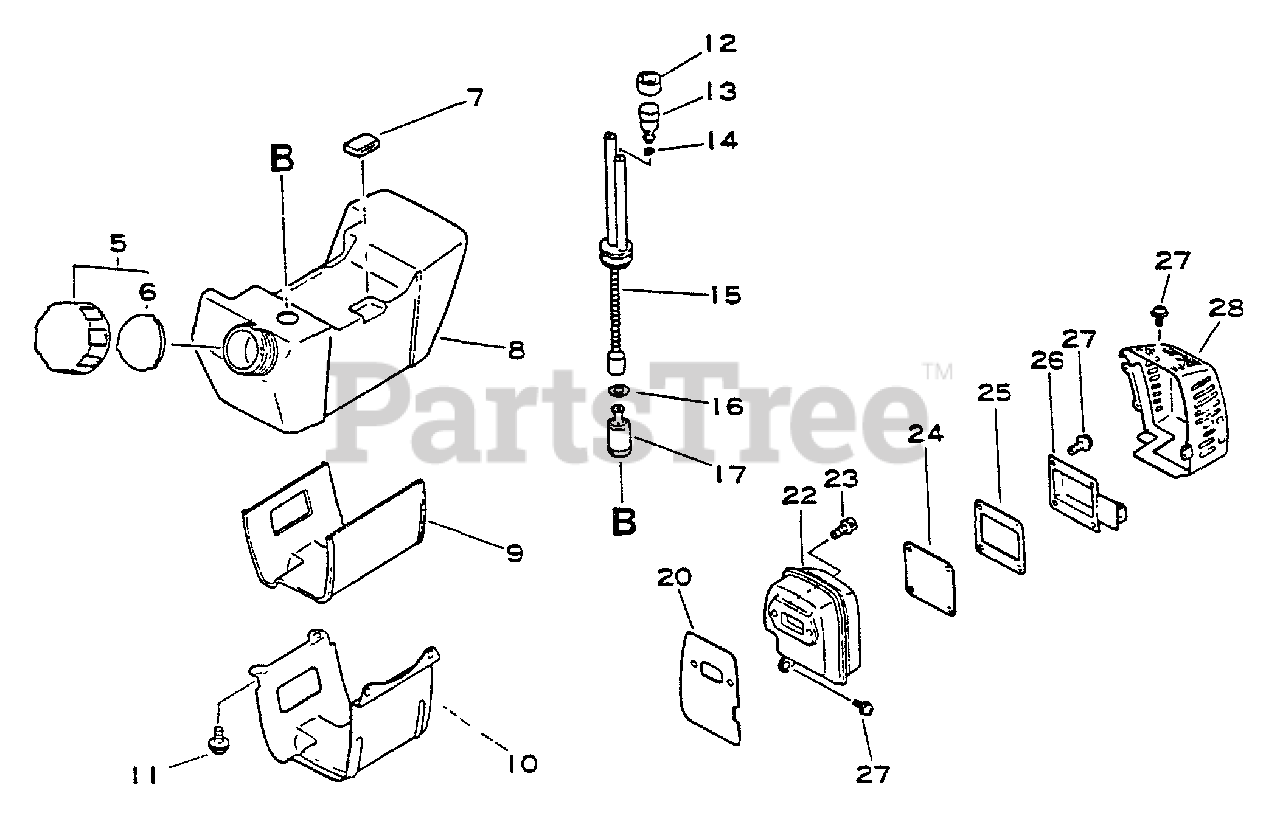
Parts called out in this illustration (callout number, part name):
5	CAP ASSY
6	GASKET, FUEL CAP
8	TANK, FUEL
10	STAND
11	SCREW 5×14
12	HOLDER, VENT
13	VENT ASSY
15	PIPE, FUEL
16	WASHER 5.5×12×0.8
17	FILTER, FUEL
20	GASKET, EXHAUST
22	MUFFLER
23	BOLT 5×20
24	SCREEN, SPARK ARRESTER
25	GASKET, EXHAUST
26	GUIDE, EXHAUST
27	SCREW 4×10
28	COVER, MUFFLER
